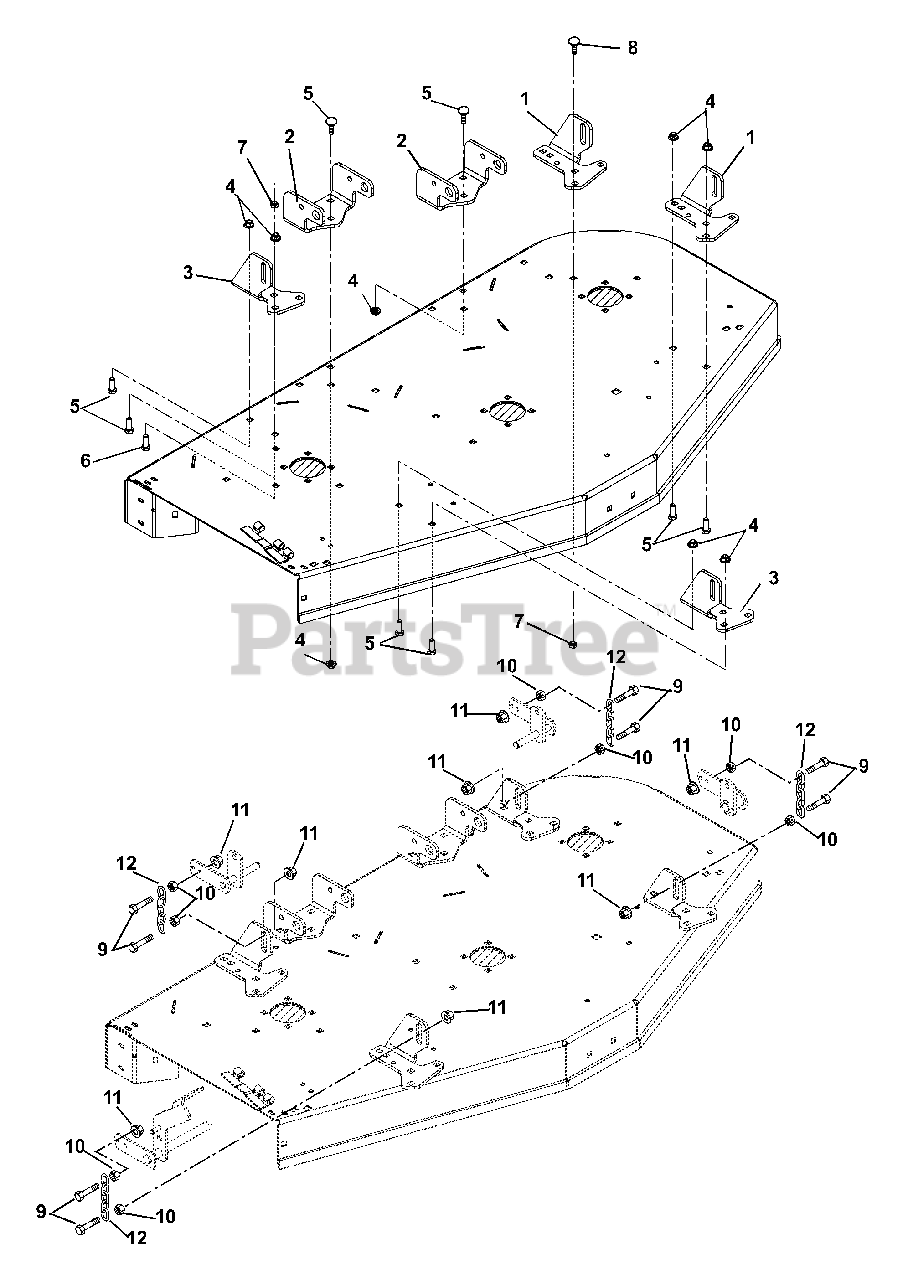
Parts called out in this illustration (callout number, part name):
1	BRKT, DECK HANGING
2	BRKT, DECK MOUNTING
3	BRKT, DECK HANGING
4	@NUT-LK-NYL-FLG .38-16 YWZC
5	@BLT-RDHDSQNK .38-16X1.00 G5YZ
6	@BLT-RDHDSQNK .38-16X1.25 G5YZ
7	@NUT-LK-CTR-JAM .375-16 YWZC
8	@BLT-RDHDSQNK .38-16X.75 G5YZ
9	BLT-HEX M12X1.75X55 GR5 YZ
10	NUT-SPNLK-FLG M12-1.75 YZ
11	NUT-LK-TOP-FLG M12-1.75 YZ
12	CHAIN, LINK
